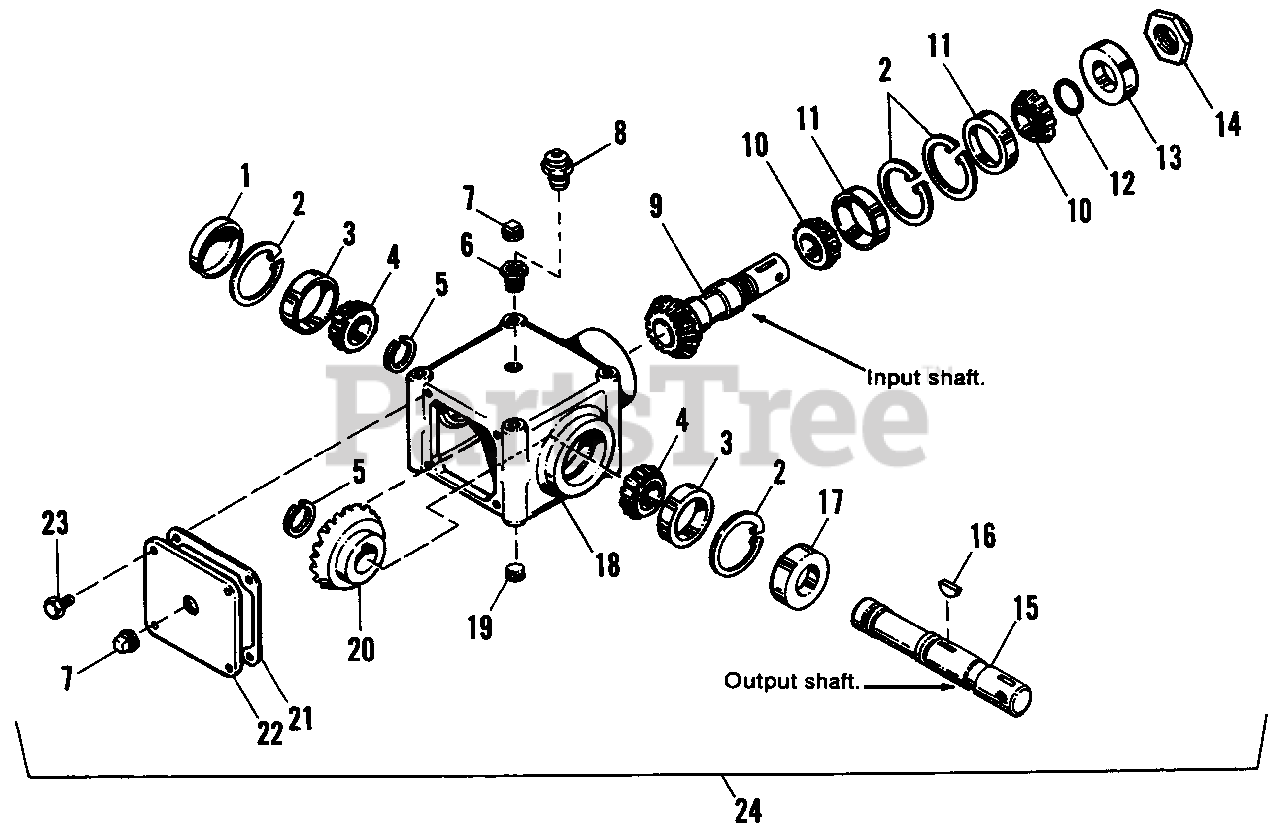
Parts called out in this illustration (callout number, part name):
2	SNAP RING
3	BEARING, Cup
4	BEARING, Cone
5	SNAP RING, Output
6	REDUCTION BUSHING, 1/8-3/8
7	PLUG, 1/8-27, N.P.T.F.
8	PLUG, Vent, 1/8 x 27 N.P.T.
9	GEAR W/SHAFT, Pinion-16T
10	BEARING, Cone
11	BEARING, Cup
13	SEAL, Input
14	NUT, Stake, Input, 1-1/8-18
15	SHAFT, Output
16	KEY, Woodruff
17	SEAL, Output
19	PLUG, Drain, 3/8-18 N.P.T.F.
20	GEAR, Bevel-32T
21	GASKET, Cover
23	CAPSCREW, Hex Hd., 5/16-18 x 5/8
24	DRIVE ASSY., Right Angle
